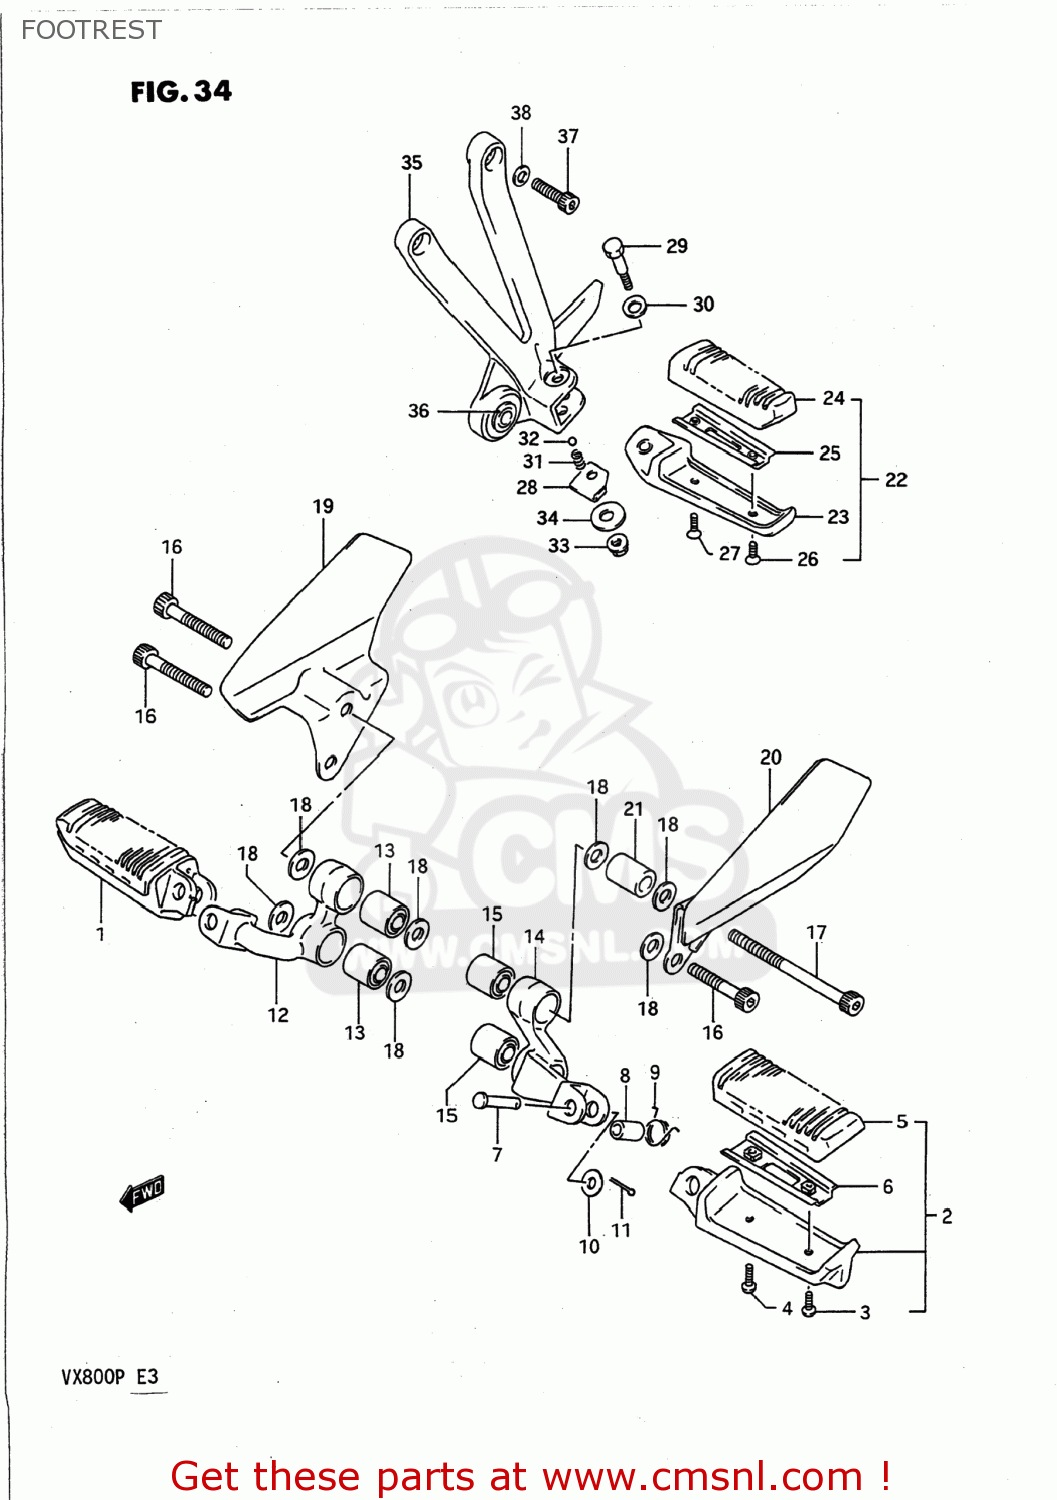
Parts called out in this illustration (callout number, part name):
1	FOOTREST ASSY,FR,R
2	FOOTREST ASSY,FR,L
3	SCREW
4	SCREW
5	RUBBER,FOOTREST
6	PLATE,FR FOOTREST RUBBER
7	PIN
8	SPACER(8.1X12X22)
9	SPRING
10	WASHER
11	PIN 20X20
12	HOLDER,FR FOOTREST,R
13	BUSH
14	HOLDER,FR FOOTREST,L
15	BUSH
16	BOLT
17	BOLT
18	WASHER(10.5X22X2.3)
19	FOOTREST
20	CUSHION,FRONT FOOTREST
21	SPACER,FR FOOTREST GUARD,L
22	FOOTREST ASSY,PILLION,R
23	BAR COMP,PILLION FOOTREST
24	RUBBER,RR FOOTREST
25	PLATE,RUBBER STOPPER
26	SCREW 5X12
27	SCREW 5X16
28	PLATE,SPRING STOP,R
29	BOLT(6X45)
30	SHIM(8.2X22X0.2)
31	SPRING
32	BALL
33	NUT
34	WASHER
35	BRACKET,PILLION FOOTREST
36	BUSH(10.2X25X19)
37	BOLT, FRONT LH
38	WASHER
